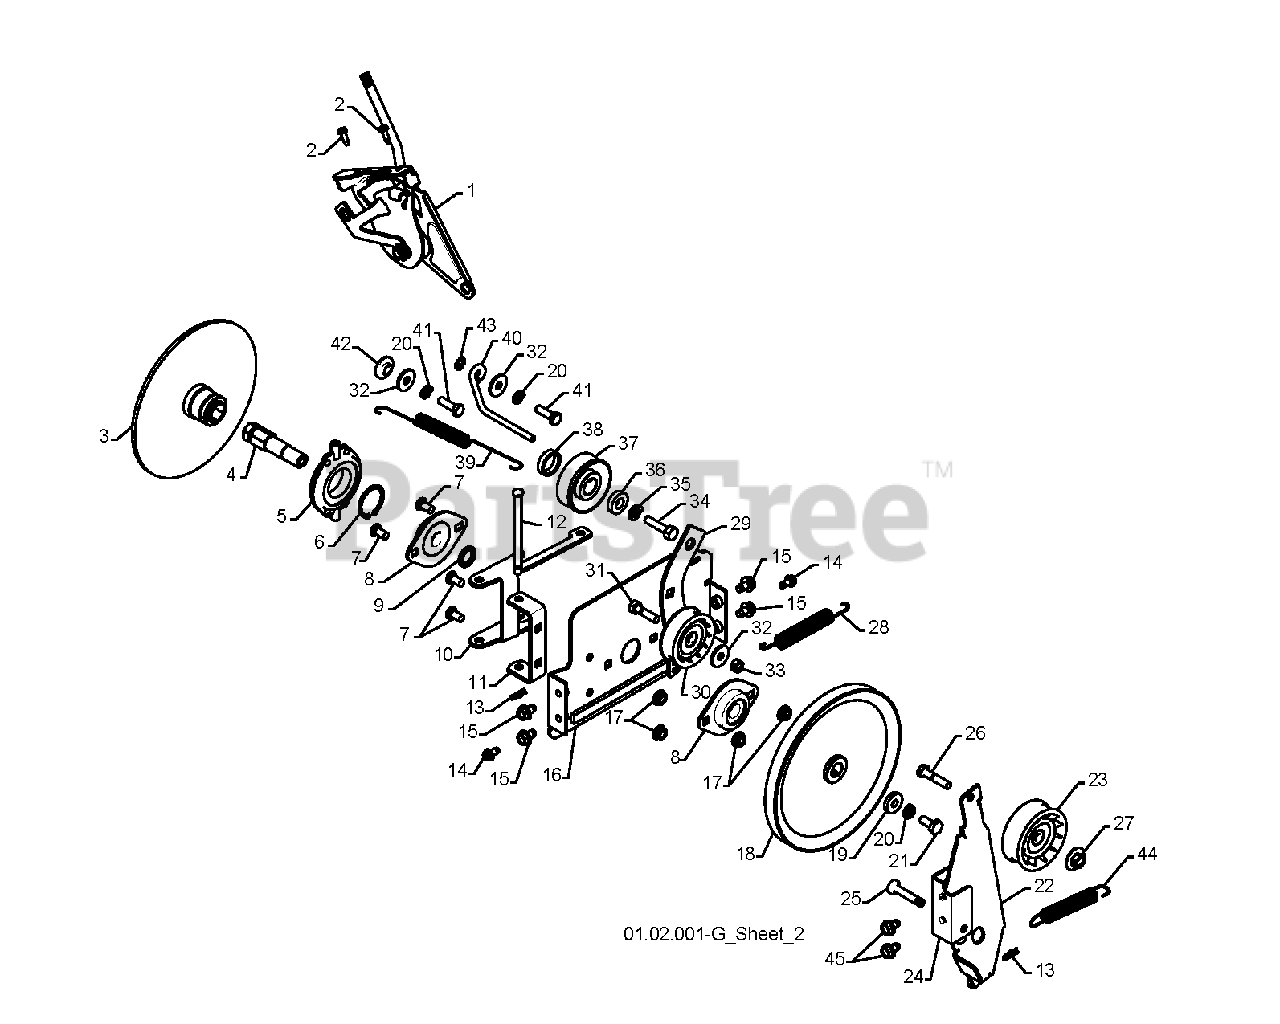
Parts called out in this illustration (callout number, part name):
1	HEAD ASSY SPEED
2	SCREW #10-24 X 5/8
3	DRIVE PLATE WELDMENT
4	SHAFT.HEX.SHORT
5	TRUNNION BEARING ASSY
6	RETAINING RING
7	BOLT
8	BEARING FLANGE
9	SPACER, BEARING
10	LEVER.SHIFTER.PLATE.BLACK
11	BRACKET, SHIFTER SUPPORT
12	PIN, PIVOT LEVER
13	RETAINER CLIP PM
14	SCREW
16	PLATE.DRIVE.MOUNTING.BLACK
17	NUT.FLANGE.5/16
18	PULLEY.TRACTION.7.75
19	WASHER, FLAT
20	LOCKWASHER
22	ARM.IDLER.BRAKE.
23	PULLEY.W/SPACER.2.75
24	BRACKET, IDLER PIVOT
25	PIN, IDLER PIVOT
26	HEX BOLT
27	NUT.FLANGE.HEX.5/16X18.BLACK
28	RP SPRING, TRACTION IDLER
29	ARM, IDLER
30	PULLEY.W/SPACER.2.25
31	BOLT.5/16-18X1-1/4 FULL.THREAD
32	STEEL WASHER
33	NUT.CENTERLOCK.5/16-
34	SCREW, HEX HD 3/8-24 X 1-3/8
35	LOCKWASHER
36	WASHER, FLAT 3/8
37	PULLEY, ENGINE TRACTION DRIVE
38	SPACER.ENGINE.PULLEY
39	SPRING.RETURN
40	GUIDE BELT
42	BUSHING, IDLER PIVOT
43	WASHER EXT TOOTH LOCK 5/16
44	SPRING, BRAKE
45	BOLT.HEX.HD.WASHER.5/16-18X.75
